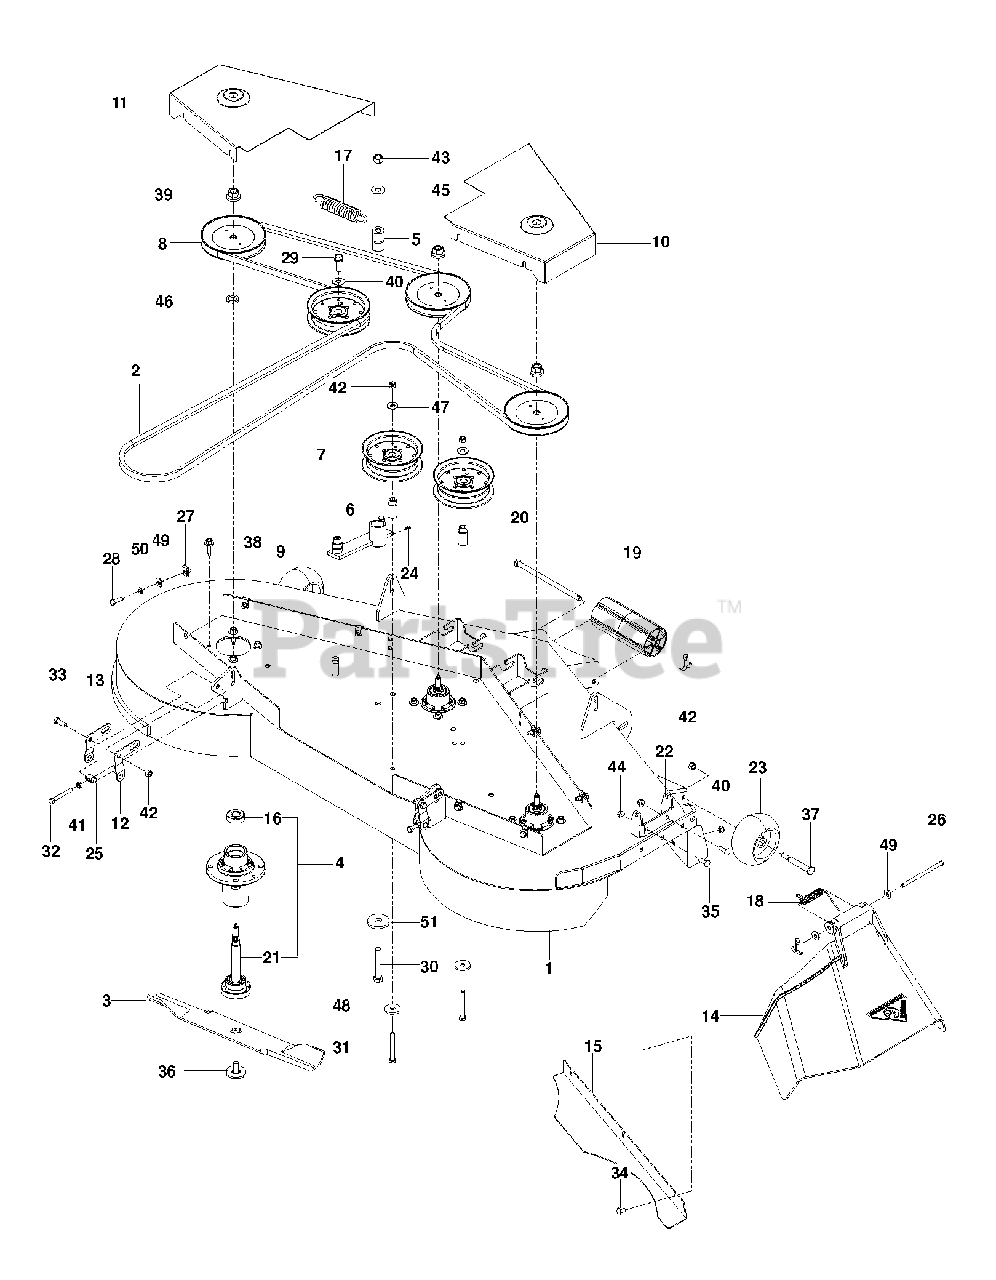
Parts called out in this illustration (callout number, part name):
1	DECK MZT 61 W/SFTY DECALS ORG
2	BELT, DECK
3	BLADE, 21"
4	MANDREL ASM, CAST IRON
5	PIVOT BUSHING
6	IDLER BUSHING
7	PULLEY, IDLER
10	BELT SHIELD, RH ORANGE
11	BELT.SHIELD.LH.ORANGE
12	PITCH, ADJUST, RT
13	PITCH, ADJUST, LT
14	DISCHARGE CHUTE 61"
15	CONFINEMENT PLATE 61
16	BEARING, BALL
18	SPRING - TORSION
19	NOSE ROLLER 48"
20	ROD.ROLLER.NOSE.NARROW.48"
21	SHAFT ASM MANDREL
22	BRACKET MZ CHUTE
23	GAUGE WHEEL
24	ZERK
25	TRUNION, PITCH
26	PIN-CLEVIS 5/16 DIA X 5.19 ZD
27	U-CLIP 5/16-18 NUT RETAINER
28	HCS 5/16C X 3/4
29	4CS 3/8C X 1 SERRATED HEAD
30	HCS 1/2C X 3 1/4
31	HCS 3/8C X 3
32	HCS 5/16-18 X 2 1/2 TPBLT
33	HCS 3/8-16X1.GRD.5.ZD
34	CARRIAGE BOLT 5/16C X 5/8"
35	BOLT.WASHER.ASM.7/16-2
36	BOLT.WASHER.ASM.7/16-2
37	SHOULDER BOLT 1/2X2-5/8 ZD SPE
38	WASHER HEAD SCREW
39	LOCKNUT - 9/16
40	NUT 5/16 NYLOC
41	NUT 5/16C HEX
42	NUT 3/8-16 NYLOC
43	RP NUT 1/2-13 HEX NYLOC ZD
44	5/16-18 NYLOC FLANGE NUT
45	WASHER 1/2 FLAT
46	WASHER-SPACER
47	RP WASHER 3/8 FLAT
48	SPINDLE WASHER
49	WASHER 5/16 FLAT
50	WASH 5/16 DISC SPRING ZD
51	WASHER, SUPPORT
